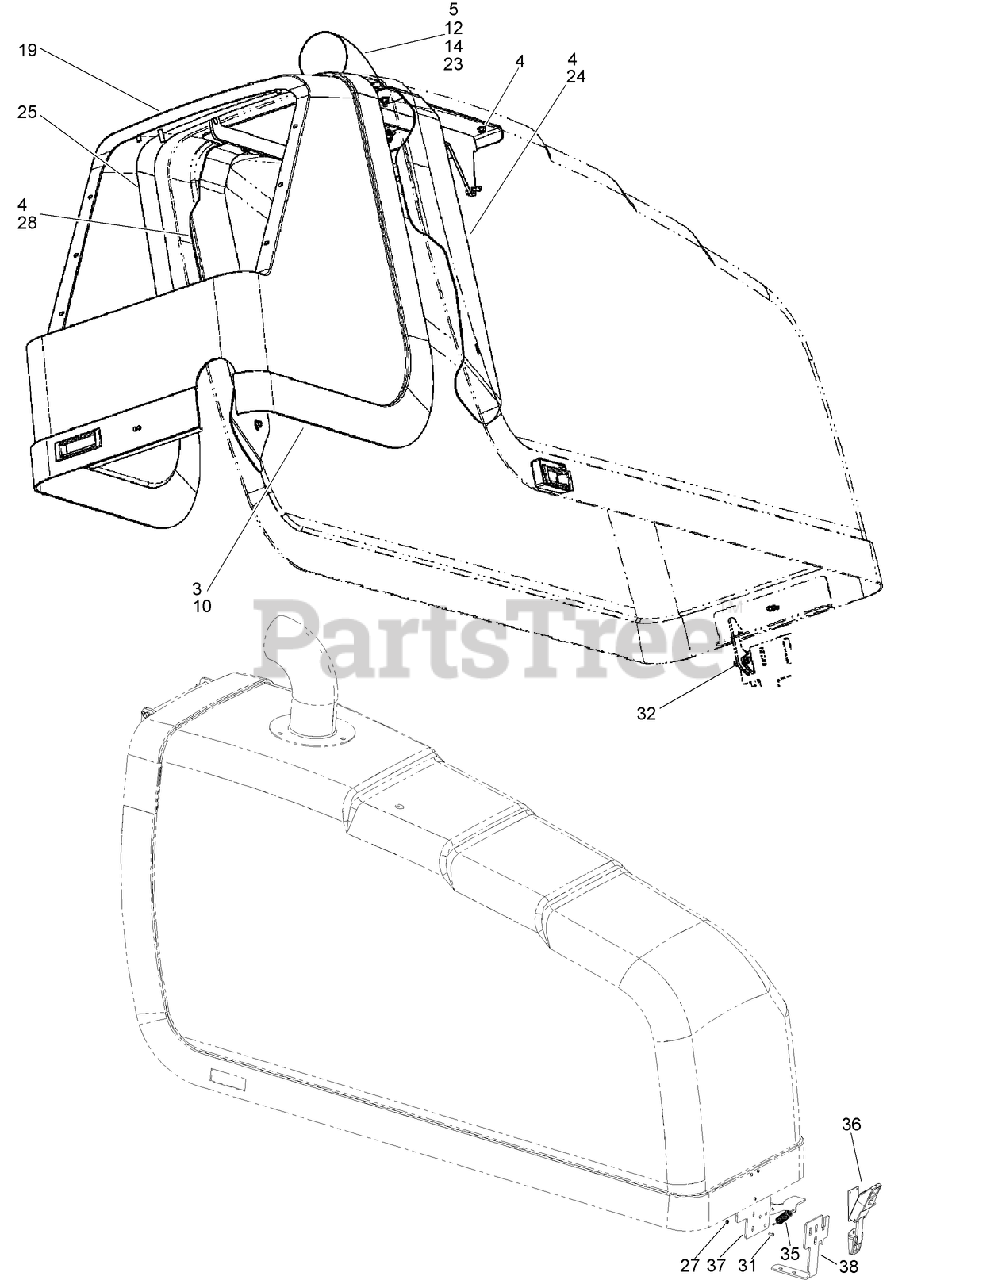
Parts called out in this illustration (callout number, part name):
3	NUT - Prev Trq 5/16 GRB ZND Direct
4	NUT-Serr Flg 3/8-16 UNC GR5 ZND
5	WASHER - .562 x 1.375 x .109 in CST ZND
10	STUD-BALL
12	NUT-FLANGE, NYLOCK
14	SCREW-HH
19	ASSEMBLY - Front Hood Mount
23	ASSEMBLY - Exhause Stack
24	PLATE - Guide
25	ASSEMBLY - Front Hood
25	FRONT HOOD ASM
27	NUT-#10-24 KEPS
28	PLATE - Guide
31	SCREW - Hex Hd #10 - 24 x 0.875 CST PHC
32	SCREW, METRIC FLANGE w/BODY - M8 x 35
35	SPRING-TENSION
36	LATCH-DRAW, LOCKABLE
37	PLATE-HOOD, STOP
38	MOUNT-HOOD
